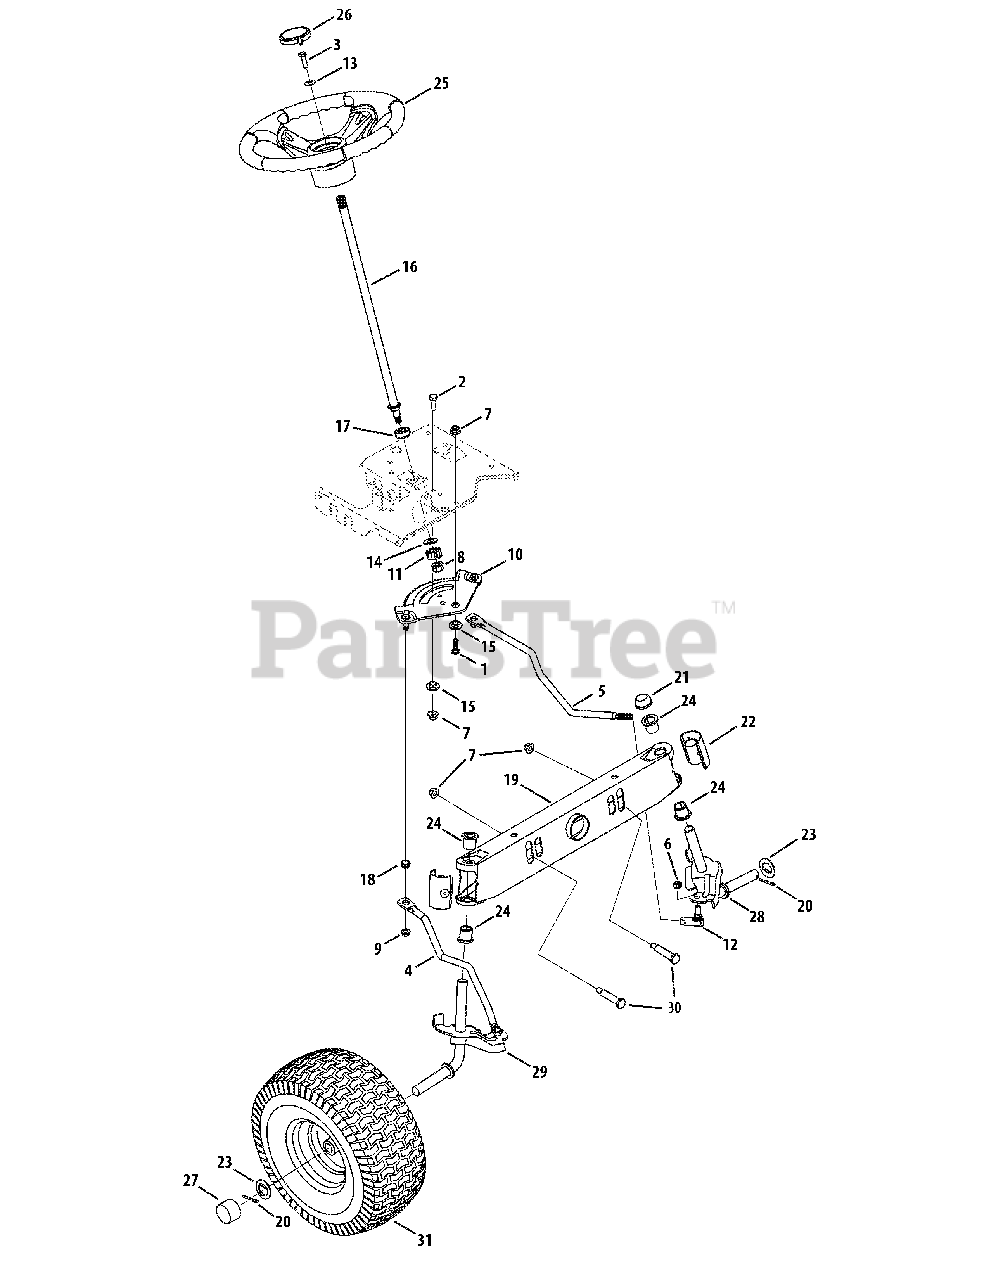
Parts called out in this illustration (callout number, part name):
1	Hex Screw, 3/8-16, 1.00, Gr5
2	Hex Screw, 3/8-16, 1.00, Gr5
3	Hex Screw, 5/16-18, 1.00, Gr5
4	Link, Drag, RH
5	Link, Drag, LH
6	Nut, Hex Lock, 3/8-24
7	Nut, Flange Lock, 3/8-16, Grf
8	Nut, Flange Lock, 7/16-20
9	Nut, Flange Lock, 5/16-18, Gr5
10	Gear, Steering, 11/90 Ratio
11	Gear, Pinion, Steering
12	Ball Joint, 7/16-20, Lock
13	Washer, Flat, .406 x .875 x .105
14	Washer, Flat, .51 x 1.12 x .06
15	Spacer, Shoulder, .38 x 1.00 x .31
16	Shaft, Steering, .625 OD x 24.25
17	Hex Flange Bearing
18	Plastic Bushing .380 ID
19	Pivot Bar Axle Assembly
20	Cotter Pin, 5/32 x 1.25 (Cast Axle)
21	Push Cap (Stamped Axle)
22	Pivot Bar End Cap w/ fitting
23	Flat Washer, .781 x 1.59
24	Flange Bearing
25	Steering Wheel
26	Steering Wheel Cap
27	Push Cap, 3/4
28	LH Axle Assembly, .750 (46" & 50")
29	RH Axle Assembly, .750 (46" & 50")
30	Shoulder Bolt, .5 x 2.38, 3/8-16
31	Wheel Assembly Complete, 15x6
